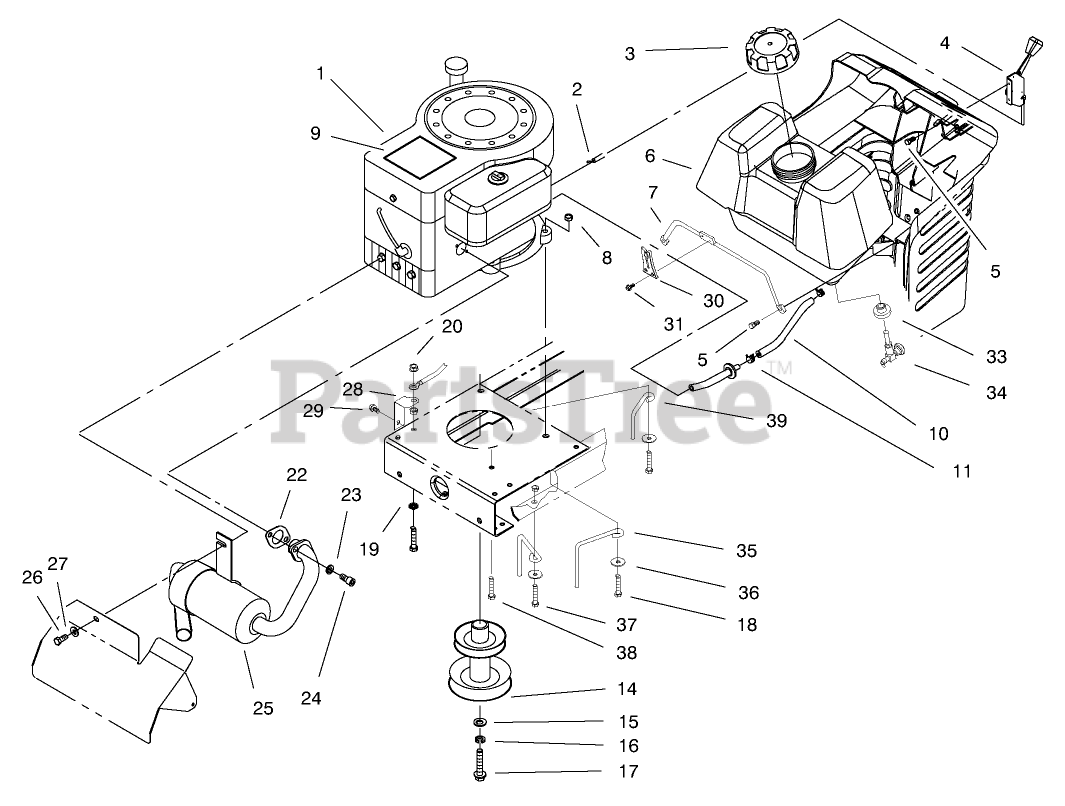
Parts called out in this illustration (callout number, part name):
1	Engine-13 H.R
2	THROTTLE CABLE ASM
3	GAS CAP ASM
4	THROTTLE CONTROL ASM
5	SCREW-SPECIAL
6	GAS TANK ASM
7	RR OIL SEAL
8	NUT-LOCK, NI
9	DECAL - ENGINE
10	HOSE-FUEL
11	CLAMP-HOSE
14	PULLEY-ENGINE ASM
15	WASHER-FLAT
16	WASHER-LOCK
17	SCREW-HH
18	SCREW-HH
19	WASHER-LOCK
20	NUT-KEPS
22	GASKET-EXHAUST
23	WASHER-LOCK
24	SCREW-HSH
25	MUFFLER
26	SCREW-HH
27	WASHER-LOCK
28	BRACKET-GROUND
29	SCREW-HWH
30	LATCH-HOOD
31	SCREW-HWH
33	BUSHING
34	VALVE-FUEL
35	GUIDE-BELT, ENGINE
36	WASHER-PIVOT
37	SCREW-HH
38	SCREW-HWH, TAPTITE
39	GUIDE-BELT, RH
